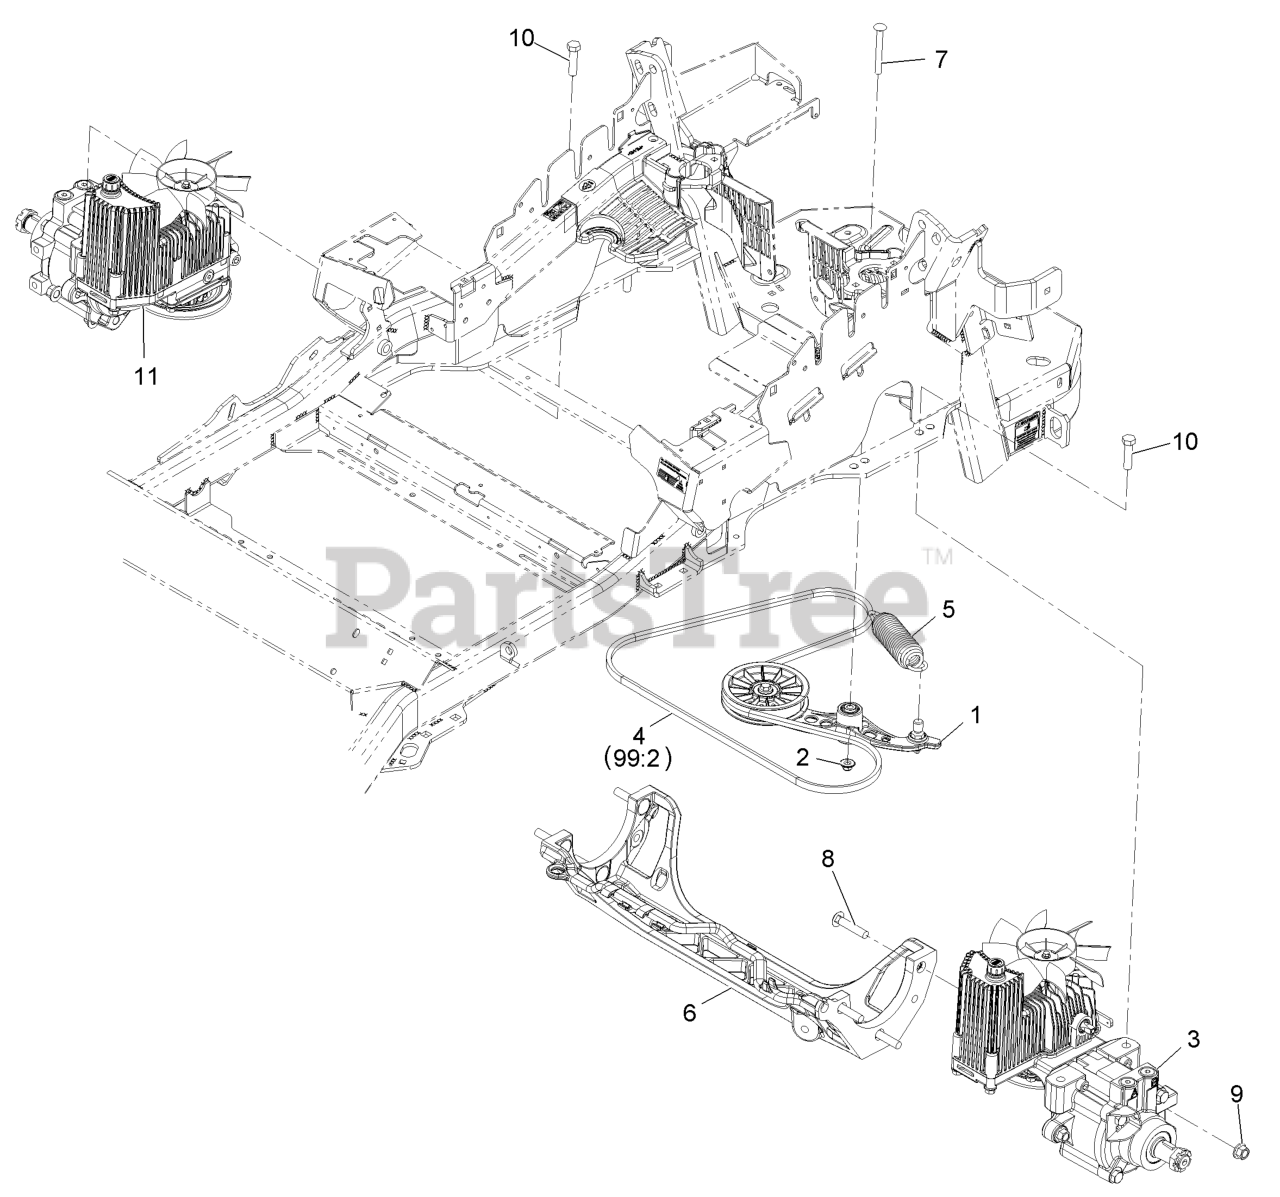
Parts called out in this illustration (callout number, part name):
1	PUMP IDLER ASM
2	Nut-Nyloc 3/8-16 Flg
4	BELT
5	SPRING-EXTENSION
7	BOLT-SHOULDER, CARRIAGE 3/8-16 X 3 1/2
8	SCREW-CARR
9	Nut-Lock 1/2-13
10	SCREW-HH
99:2	BELT
